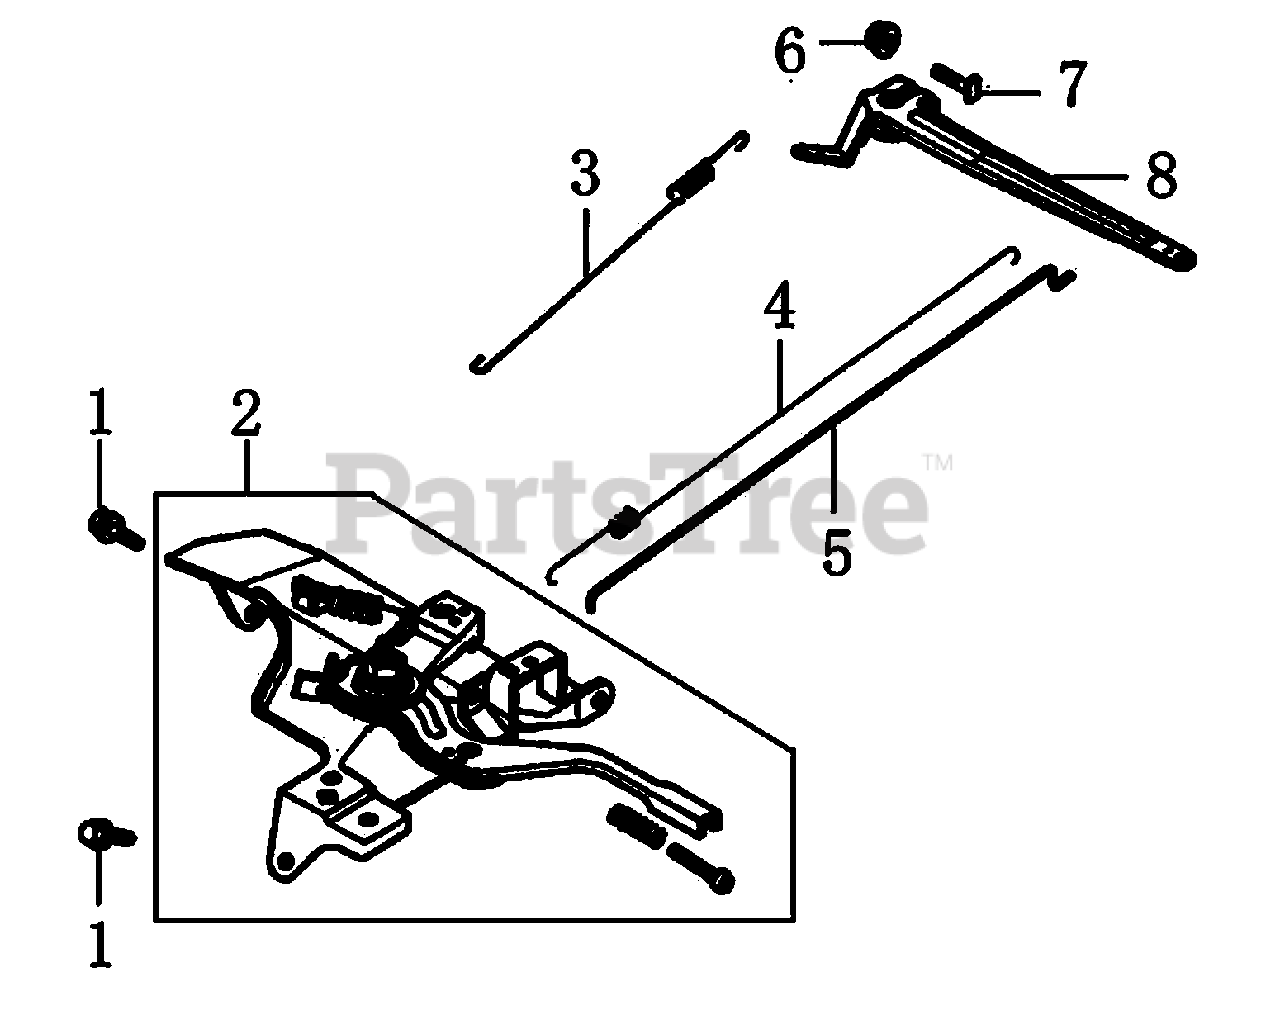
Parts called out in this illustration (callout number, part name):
1	NUT, FLANGE M6
2	CONTROL ASSY
3	SPRING , CABLE RETURN
4	SPRING, THROTTLE RETURN
5	ROD, GOVERNOR
6	NUT, FLANGE M6
7	BOLT, GOVERNOR ARM
8	ARM, GOVERNOR
